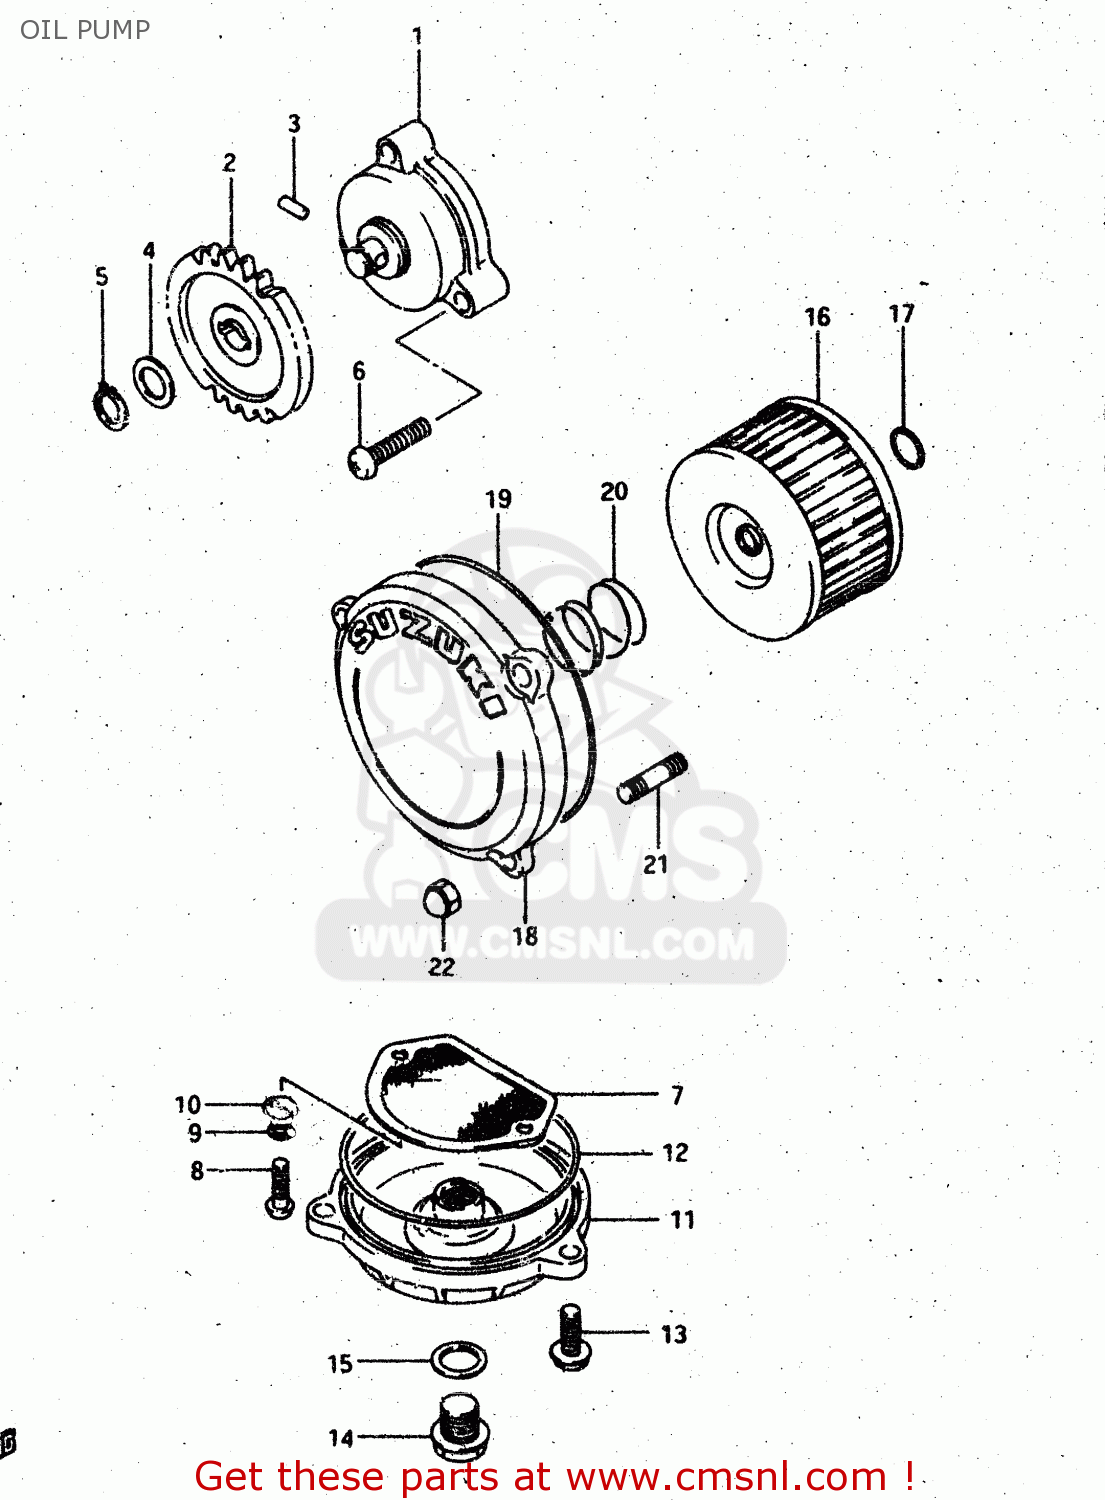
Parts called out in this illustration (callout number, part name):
1	PUMP ASSY,ENGINE OIL
2	GEAR,OIL PUMP DRIVEN
3	PIN(4X15.8)
4	SHIM
5	CIRCLIP
6	SCREW
7	STRAINER,ENGINE OIL
8	SCREW 5X12
9	LOCK WASHER
10	WASHER
11	CAP,OIL STRAINER
12	O RING(D:2.4,ID:85)
13	BOLT,REAR
14	PLUG
15	GASKET(14X19.2X2) (NAS)
16	FILTER,ENGINE OIL
17	O RING(D:2.4,ID:15.8)
18	CAP,OIL FILTER
19	O RING(D:2.4,ID:73)
20	SPRING
21	STUD 6X12
22	NUT 6MM
